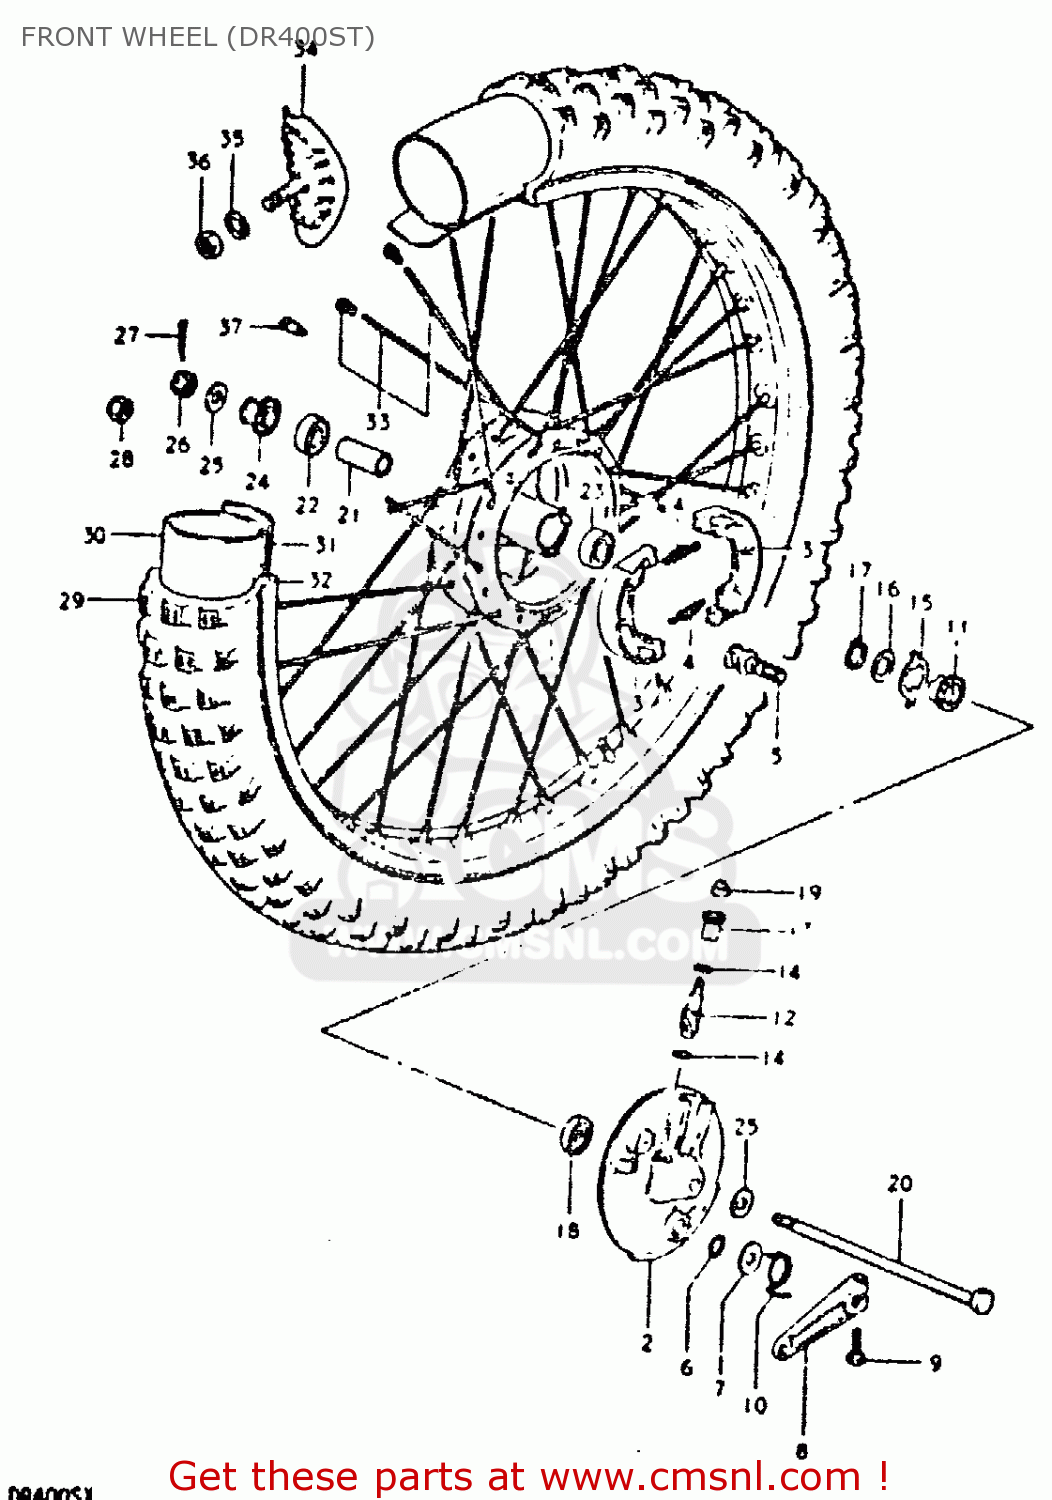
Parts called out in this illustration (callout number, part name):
1	DRUM,FRONT HUB
2	PANEL, FRONT HUB
3	SHOE,BRAKE (MCA)
4	SPRING
5	CAM,FRONT BRAKE
6	O-RING,BOSS
7	SPACER
8	LEVER,FRONT BRAKE CAM
9	BOLT
10	SPRING
11	GEAR,SPEEDOMETER
12	PINION,SPEEDOMETER
13	BUSHING,SPEEDOMETER PINION
14	WASHER (5.1X9X0.4)
15	DRIVER,SPEEDOMETER GEAR
16	WASHER(22.5X27X1)
17	CIRCLIP
18	SEAL,OIL(26X38X4)
19	SEAL,OIL(6X10X3)
20	AXLE,REAR
21	SPACER (12.6X19X52)
22	BEARING, RH
23	BEARING
24	SPACER,FRONT AXLE,RIGHT
25	WASHER
26	NUT, REAR AXLE
27	COTTER PIN
29	TIRE,FRONT
30	TUBE
31	PROTECTOR,WHEEL,INNER
32	RIM,FRONT WHEEL
33	SPOKE SET,FRONT
34	STOPPER,BEAD
35	WASHER
36	NUT
37	BALANCER,WHEEL (50G)
